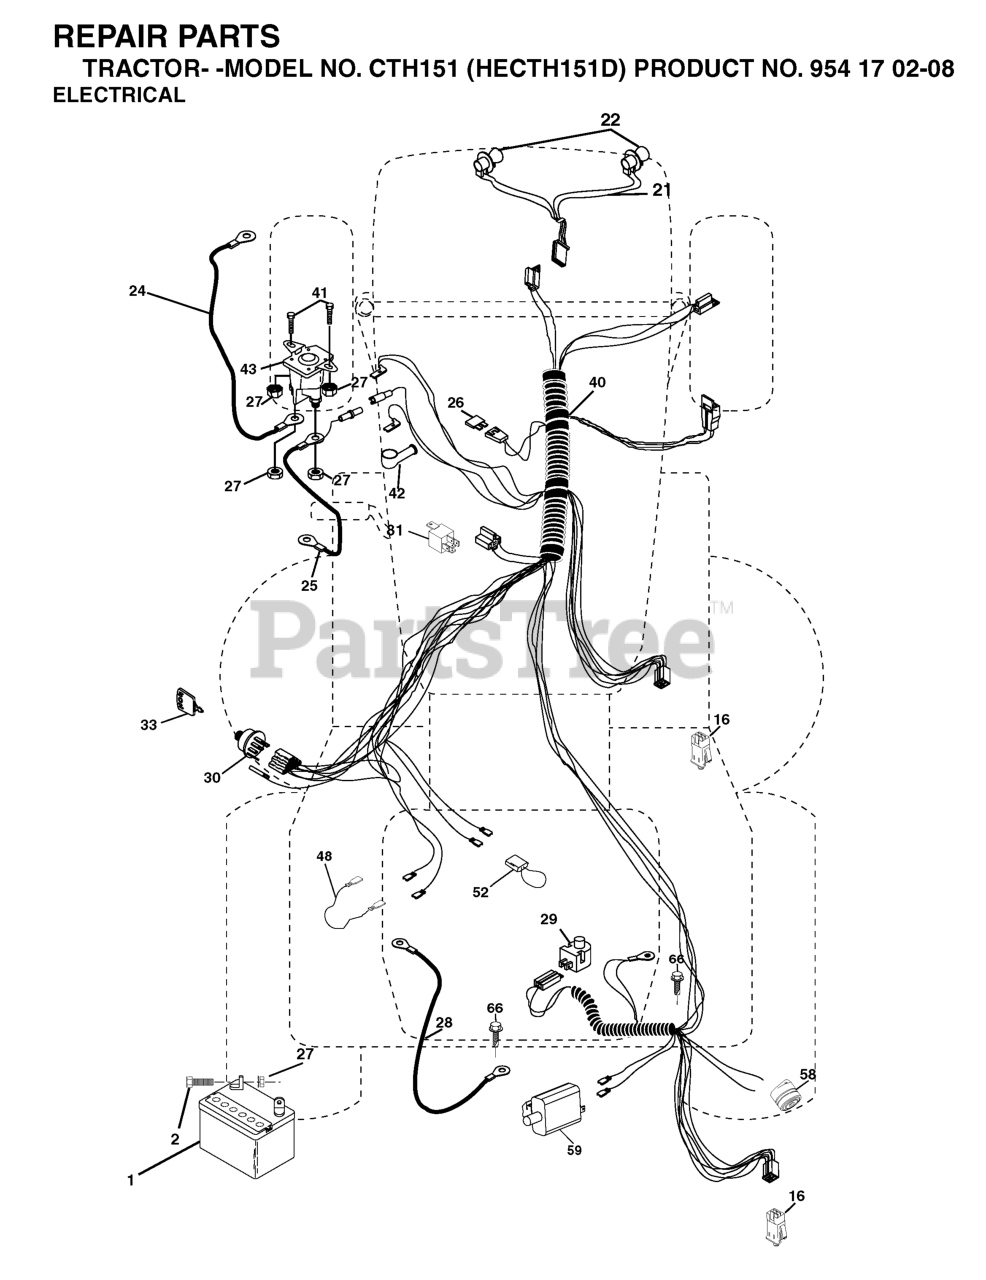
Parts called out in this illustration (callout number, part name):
1	BATTERY 12V .35 AMP
2	BOLT.HEX.1/4.X.3/4.DICHROMATE
16	SWITCH INTERLOOK PUSH-IN
21	HARNESS.W/LIGHT SOCKET
24	BATTERY CABLE GT
25	CABLE BATTERY
26	FUSE 20AMP
27	NUT
28	CABLE GROUND
29	RP.SWITCH.PLUNGER.NC.GRAY
30	IGNITION SWITCH
33	KEY MLD GEN DELTA
41	BOLT
42	TERMINAL COVER
43	SOLENOID
48	ADAPTER.AMMETER
52	WIRE PROTECTION LOOP
58	BUZZER
59	.WITCH.FULL BAGGER.INDICATOR
81	RELAY.ASSY.T
